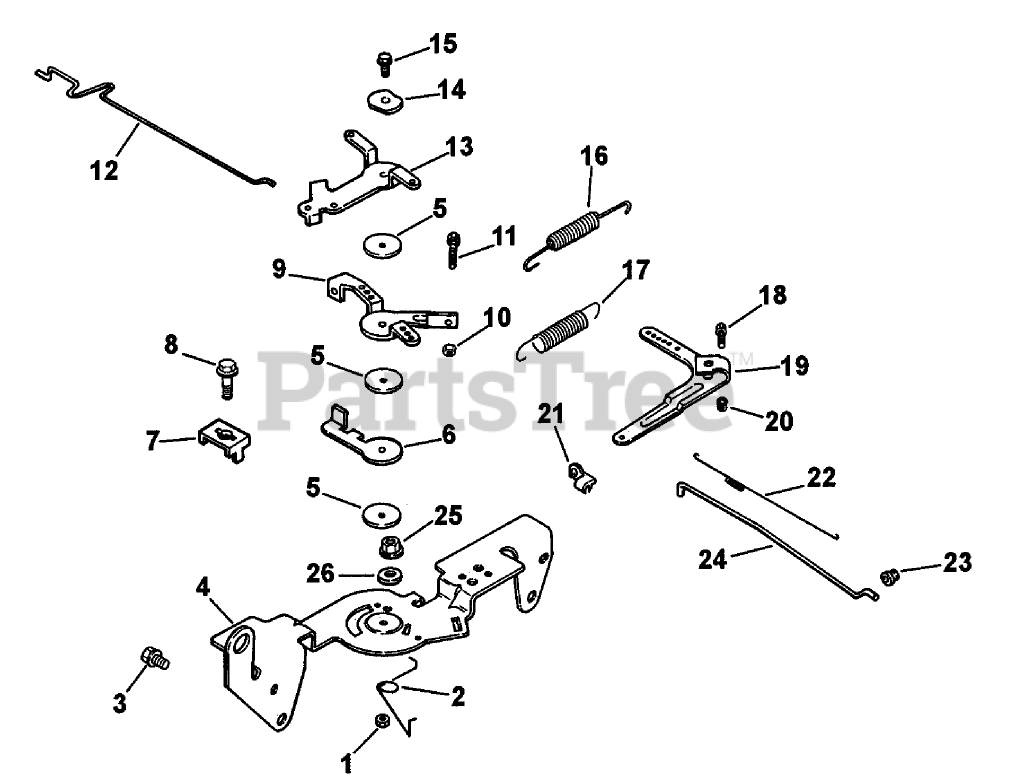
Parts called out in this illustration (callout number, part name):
1	NUT-LOCK (M5X.8)
2	SPRING-RETURN, CHOKE
3	SCREW-FLANGE, THREAD FORMING (M6X1.0X16)
4	Bracket-Control
5	WASHER-FLAT (5.5MM)
6	Lever-Actuator, Throttle
7	CLAMP-CABLE
8	SCREW-FLANGE, THREAD FORMING (M5X0.8X16)
9	Lever-Control, Throttle
10	NUT (M4X0.7)
11	Screw (M4x0.7x30)
12	Linkage-Choke
13	LEVER-CHOKE
14	WASHER-SPRING (1/4)
15	SCREW-FLANGE, THREAD FORMING (M5X.8X20)
16	Spring-Limiter, Throttle
17	Spring-Governor
18	BOLT-SQ NECK, RD HD (M6X1.0X25)
19	Lever-Governor
20	NUT-FLANGE (M6X1.0)
21	BUSHING-RETAINING, LINKAGE
22	SPRING-LINKAGE
23	BUSHING-LINKAGE, THROTTLE
24	Linkage-Throttle
25	Nut-HF (M5x0.8)
26	Washer-Lock (.25)
